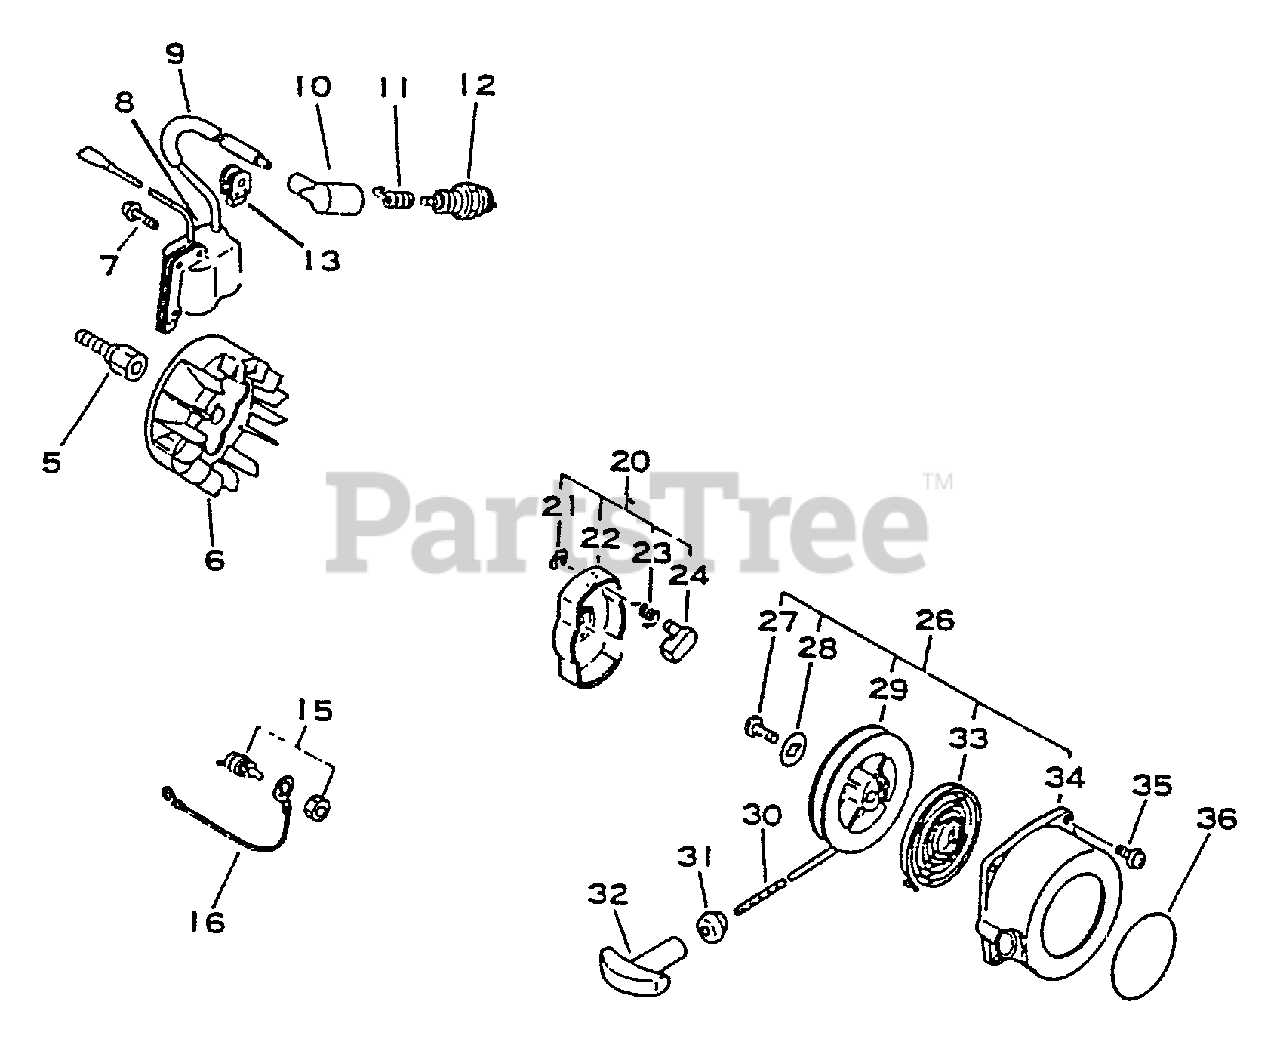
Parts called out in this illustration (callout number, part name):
5	HUB, FAN
6	FLYWHEEL
7	SCREW - 4×22
8	COIL, IGNITION
10	CAP, SPARK PLUG
11	TERMINAL, SPARK PLUG
12	SPARK PLUG - BPM7A
12	SPARK PLUG - BPMR7A
15	SWITCH, ON-OFF
16	LEAD - GROUND
20	STARTER PAWL ASSY
21	E-RING 4
22	CATCHER, PAWL
23	SPRING, RETURN
24	PAWL, STARTER
26	STARTER ASSY
28	WASHER
29	REEL, ROPE
30	ROPE, STARTER
31	GUIDE, ROPE
32	GRIP, STARTER
33	SPRING, RECOIL
34	CASE, RECOIL STARTER
35	SCREW 4×18
36	LABEL - ECHO
